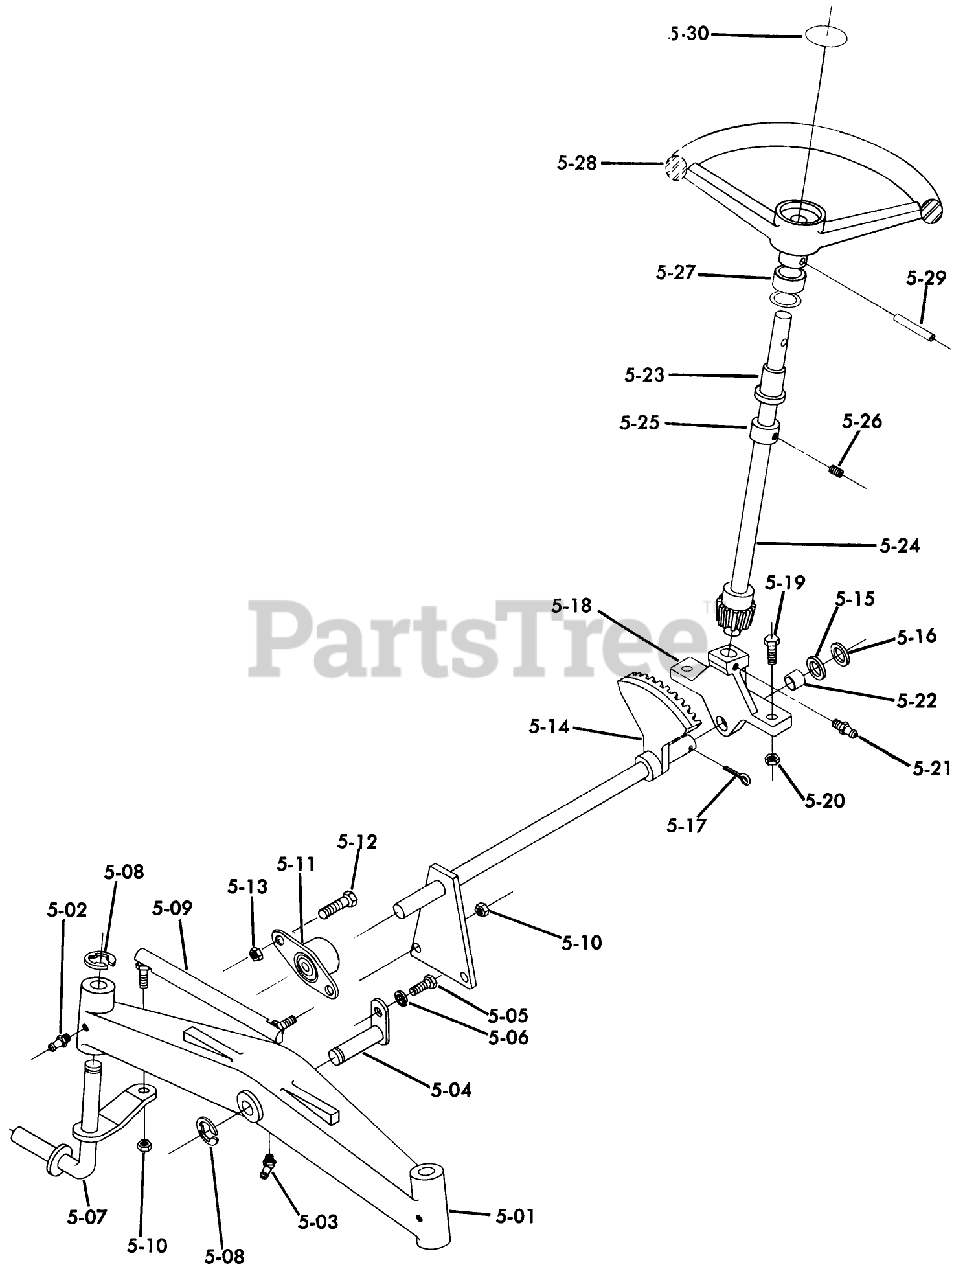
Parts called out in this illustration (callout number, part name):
5-03	FITTING-GREASE
5-04	PIN AND PLATE ASM
5-08	E-RING
5-11	BEARING-FLANGED
5-15	WASHER-SHIM
5-16	WASHER
5-22	BEARING-BRONZE
5-23	BEARING
